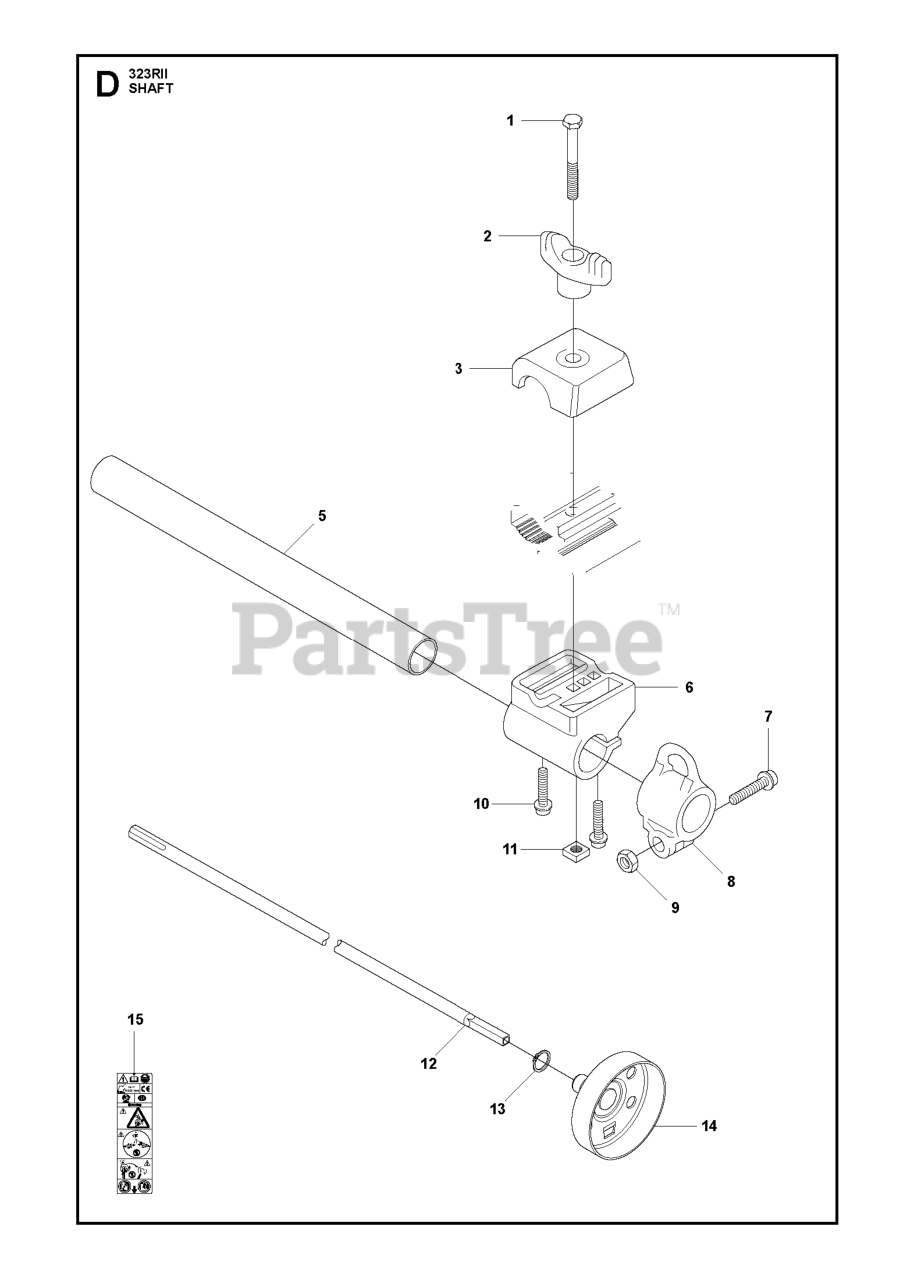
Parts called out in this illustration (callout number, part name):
5	DRIVE TUBE ASSEMBLY
7	SCREW
8	HARNESS HOLDER
12	DRIVE SHAFT
13	RETAINING RING SGA 10
14	CLUTCH DRUM
15	LABEL WARNING TRIMMERS AND BRU
